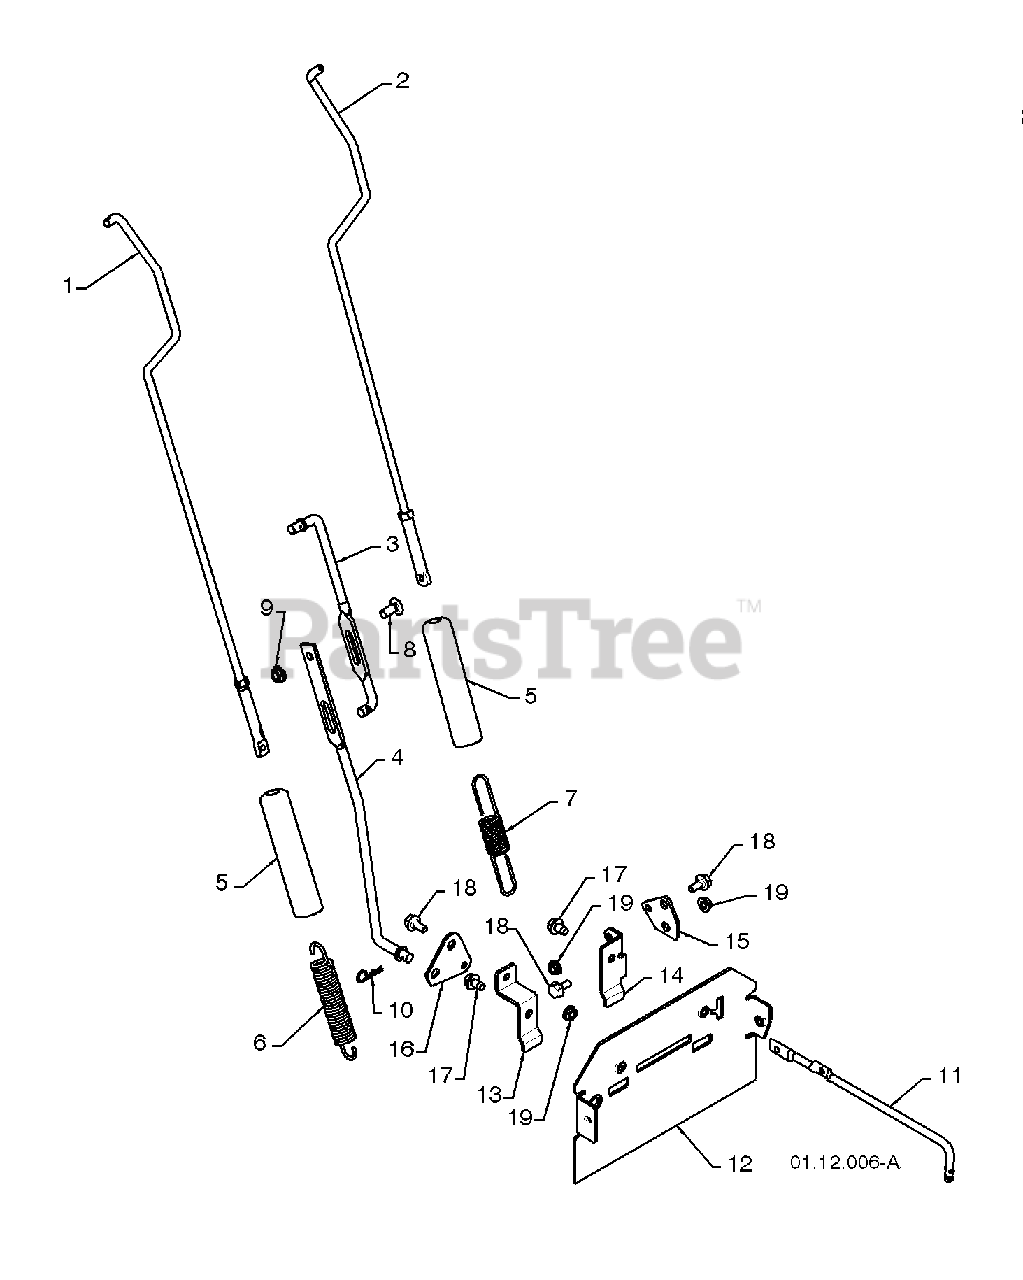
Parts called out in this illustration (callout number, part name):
1	IMPELLER ROD ASSEMBLY
2	TRACTION ROD ASSEMBLY
3	SHIFTER ROD TOP
4	SHIFTER ROD BOTTOM
5	SPRING SLEEVE
6	IMPELLER SPRING
7	TRACTION SPRING
8	CARRIAGE BOLT 5/16-18 X .750
9	NUT 5/16-18
11	CLUTCH ROD
12	REAR PLATE
13	SHIFTER PLATE BRACKET
14	CLUTCH PLATE BRACKET
15	CLUTCH PLATE
16	SHIFTER PLATE
17	BOLT 5/16-18 X .500
18	SHOULDER BOLT 1/4-20 X .500
19	NUT 1/4-20
